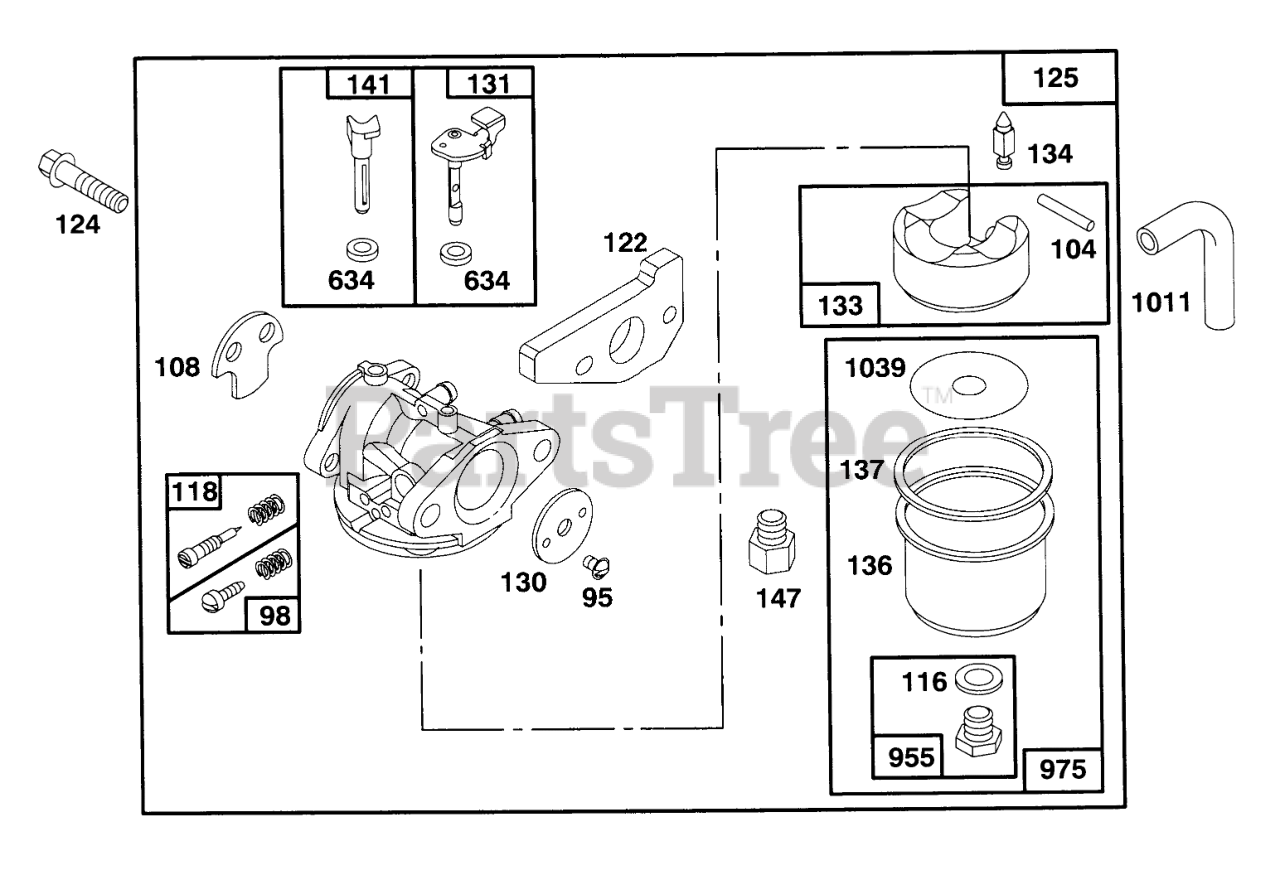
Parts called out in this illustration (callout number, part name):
95	SCREW - ROUND HEAD
98	IDLE ADJUSTING SCREW
104	FLOAT HINGE PIN
108	CHOKE VALVE
116	SEALING GASKET
118	VALVE KIT - NEEDLE
122	ADAPTER ASSEMBLY
124	HEX HEAD SCREW
125	CARBURETOR ASSEMBLY
130	THROTTLE VALVE
131	THROTTLE SHAFT
133	FLOAT-CARBURETOR
134	Valve-Inlet (Includes Seat)
136	FLOAT BOWL
137	FLOAT BOWL GASKET
141	CHOKE SHAFT
147	JET ADAPTER
634	SEAL WASHER
955	HEX HEAD SCREW
975	CARBURETOR BOWL ASM
1011	VENT TUBE
1039	FLOAT LIMITER
